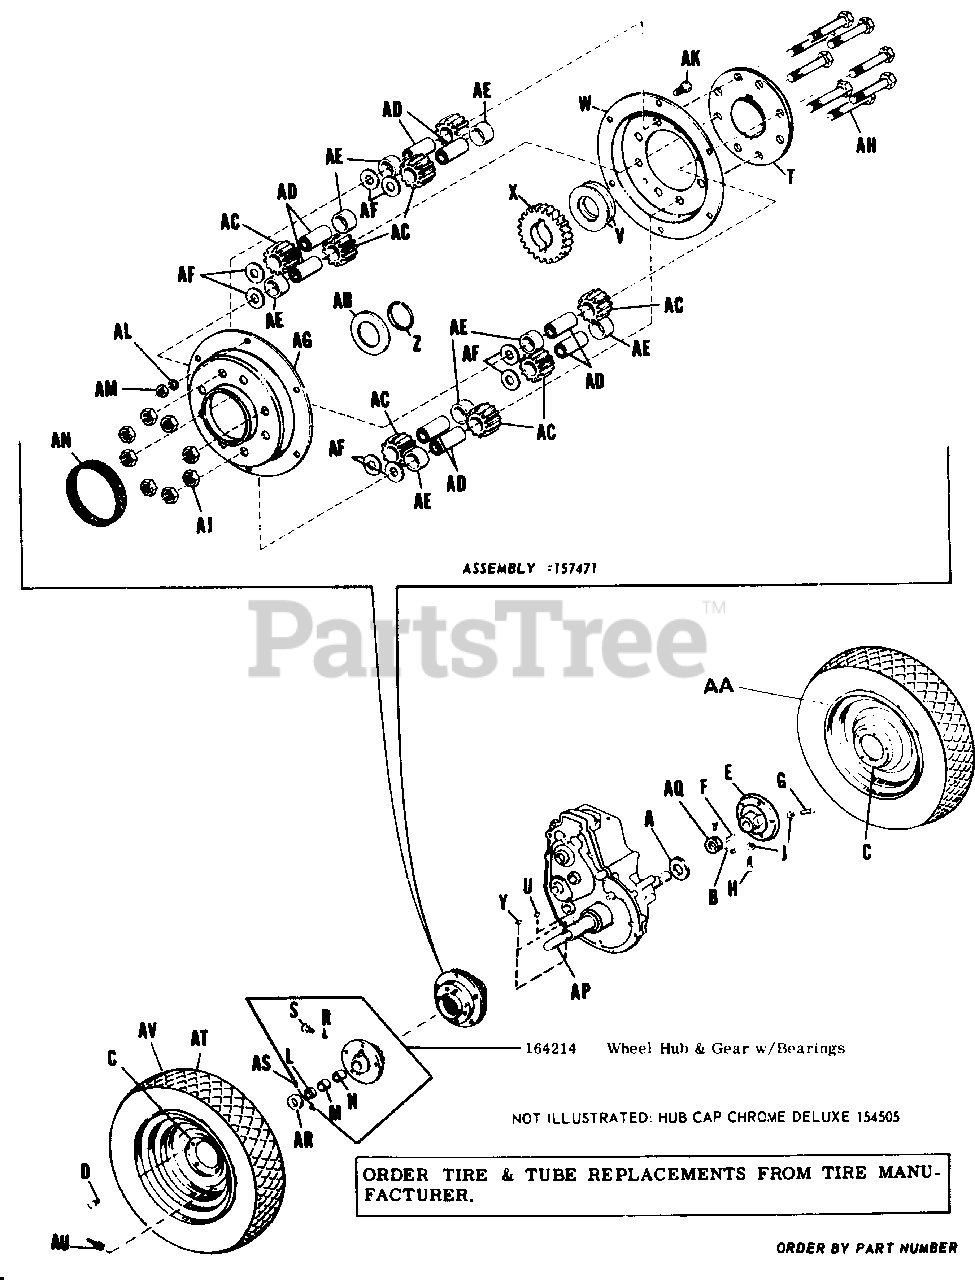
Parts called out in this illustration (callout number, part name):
B	Set Screw, 5/16"-18 x 3/8" Lg.
C	Wheel Drive
E	L.H. Wheel Hub
G	Set Screw, 3/8"-16 x 1 1/2" Lg.
H	Set Screw 3/8"-16 x 1" Lg.
J	Hex. Jam Nut, 3/8"-16
M	Nylon Bearing
R	Nylon Plug
S	Control Traction Bolt, 7/16"-20 x 1/2" Lg.
T	Differential Carrier
V	Axle Washer
W	Differential Cover
X	Differential Gear
Y	Hi-Pro Key
Z	Retaining Ring
AA	Tube (For Service Only)
AB	Axle Washer
AC	Differential Pinion
AD	Pinion Differential Spindle
AE	Differential Spacer
AF	Plain Washer
AG	Differential Cover
AH	Hex. Cap Screw, 3/8"-16 x 2 1/2"
AJ	Full Lock Hex. Nut, 3/8"-16
AK	Hex. Cap Screw, 1/4"-20 x 5/8"
AL	Lock Washer, 1/4"
AM	Full Hex. Nut, 1/4"-20
AN	Differential Cover Seal
AQ	Axle Collar
AR	Axle Collar
AS	Set Screw, 5/16"-18 x 3/8"
AT	Tire 10 1/2" x 12
AU	Valve Stem
AV	Wheel & Tire Assy.
